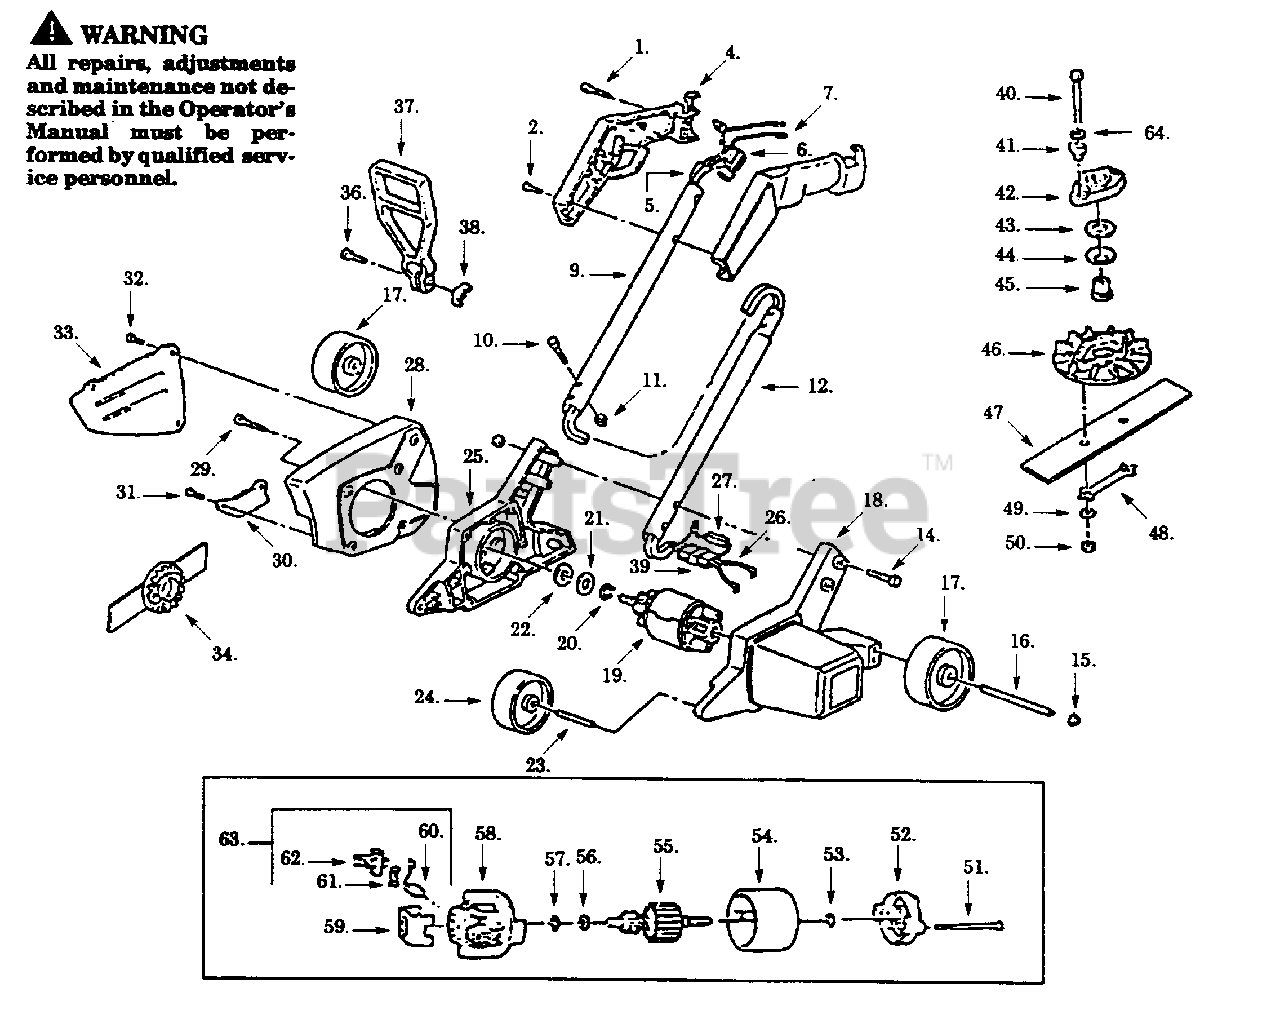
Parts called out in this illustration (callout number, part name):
4	Handle Set
5	Harness Ass'y.
6	Trigger Switch
7	Wire Blade Ass'y.
9	Upper Tube
12	Lower Tube
16	Rear Axle
17	Rear Wheel
18	Motor Cover
19	Motor Ass'y.
20	Retaining Ring
23	Front Axle
24	Front Wheel
26	P.C. Board Ass'y.
27	Resister
28	Housing Guard
30	Blade Guide
33	Blade Guard
34	Blade Ass'y.
37	Assist Handle
38	Wing Nut
41	Insulating Sleeve
42	Clutch Plate
44	Spring Washer
45	Clutch Sleeve
48	Lock Strap
49	Lockwasher
52	Endbell Ass'y. (Drive)
54	Field Ass'y.
55	Armature Ass'y.
58	Endbell Ass'y. (Brush)
59	Insulator
60	Carbon Brush
61	Spring Brush
62	Brush Holder
63	Brush Kit (Incl. 60,61,62)
